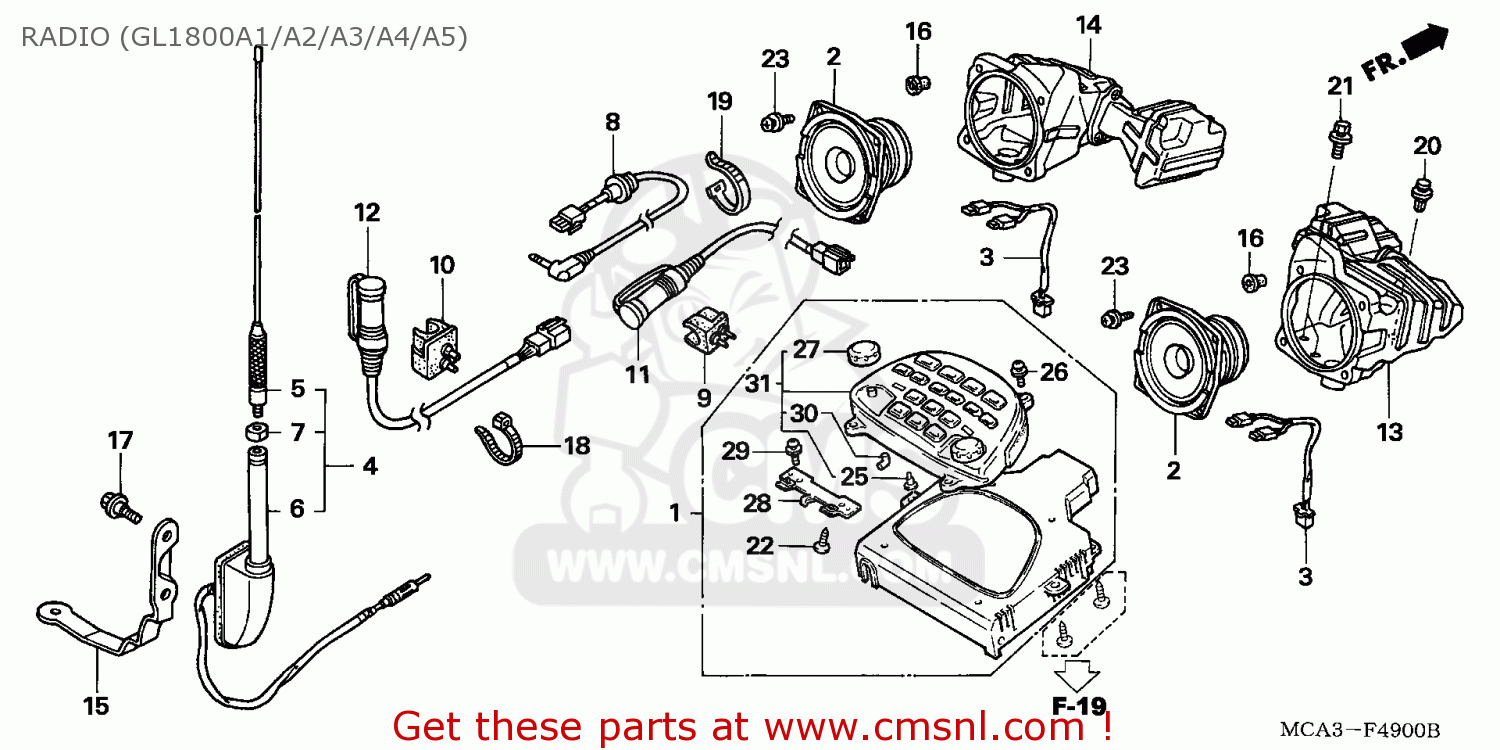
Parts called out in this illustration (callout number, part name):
1	AUDIO UNIT,COMP
2	SPEAKER UNIT,FR
4	ANTENNA ASSY RADI
5	ANTENNA ELEMENT
6	ANTENNA FEEDER CO
7	NUT,ANTENNA
8	CORD COMP,AUX
9	CONNECTOR HOLDER
10	CONNECTOR HOLDER,
11	JUNCTION LEAD,HEA
12	JUNCTION LEAD,HEA
13	BOX ASSY,R SPEAKE
14	BOX ASSY,L SPEAKE
15	PLATE,ANTENNA SET
16	NUT,COWL SET M5X0
17	BOLT,FLANGE 6MM
18	BAND,WIRE
19	BAND,WIRE
20	CLIP, SPLASH SHIELD
21	BOLT-WASH.,6X12
22	SCREW-WASH,5X10
23	SCREW-WASHER,5X16
25	BULB NEO WEDGE
26	SCREWS WITHCAPTIV
27	AUDIO KNOB
28	STAY,TOP SHELTER
29	SCREWS WITHCAPTIV
30	DRAIN PIPE
31	UPPER CASE COMP
